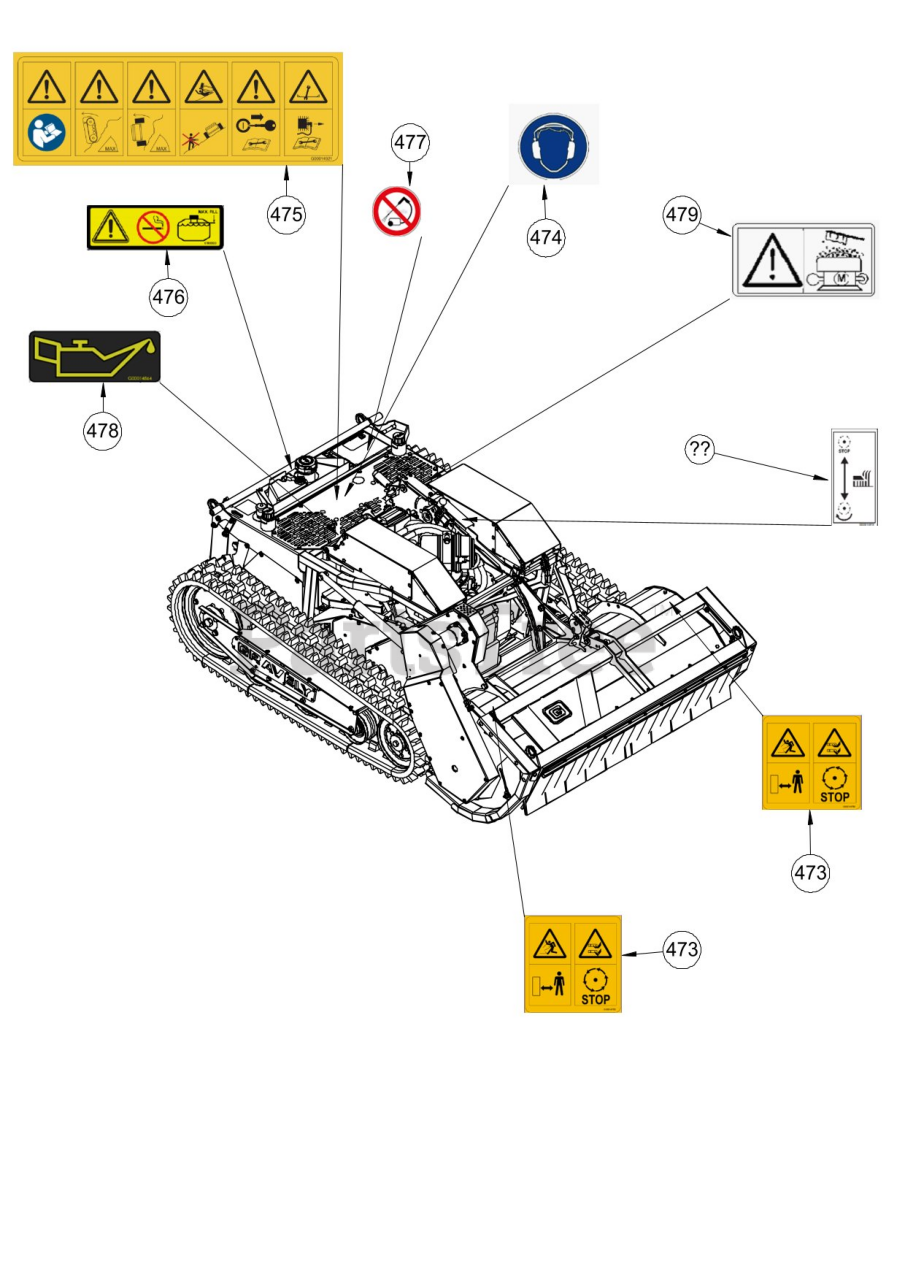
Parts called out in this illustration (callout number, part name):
473	DECAL, DECK SAFETY
474	DECAL, SAFETY - HEARING PROTECTION
475	DECAL, SAFETY - OPERATION
476	DECAL, FUEL WARNING
477	DECAL, NO HIGH PRESSURE CLEANING
478	DECAL, CHECK ENGINE OIL
479	DECAL, CLEAN FAN GRILL
